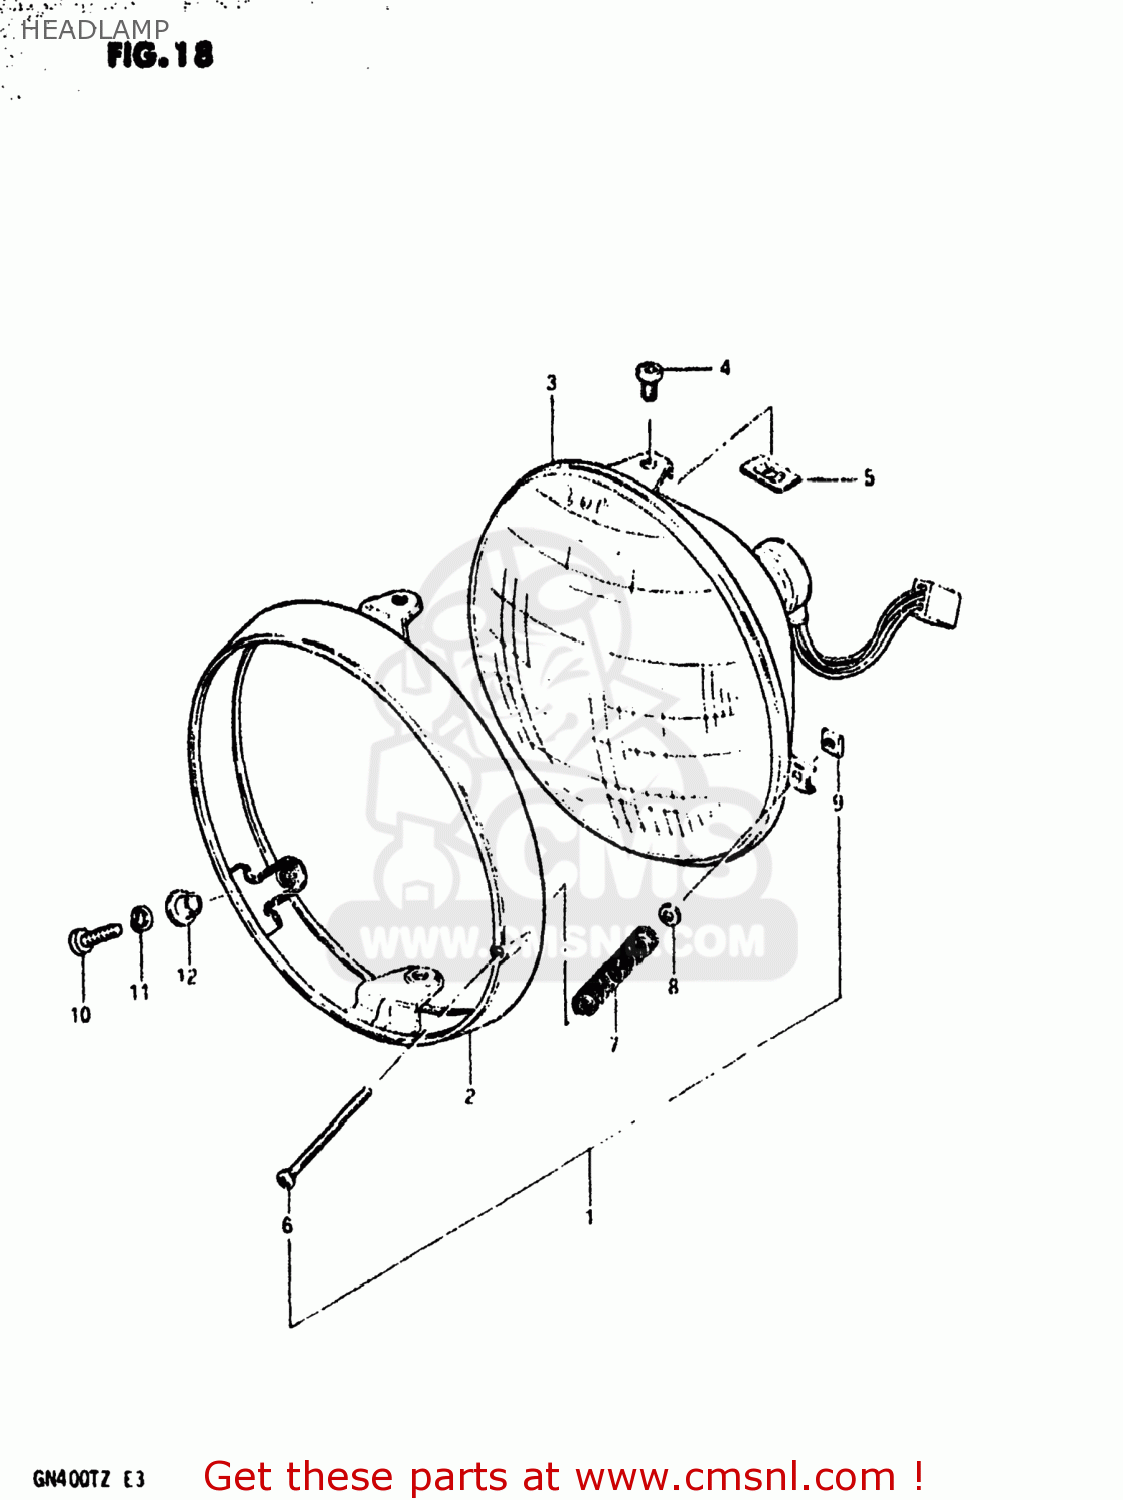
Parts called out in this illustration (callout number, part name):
1	HEADLAMP ASSEMBLY
2	RIM,HEADLAMP
3	LAMP UNIT
4	SCREW
5	NUT,ADJUSTING
6	SCREW
7	SPRING,HEADLAMP ADJUST
8	WASHER
9	NUT,HEADLAMP ADJUSTER
10	SCREW
11	WASHER,LOCK
12	WASHER
